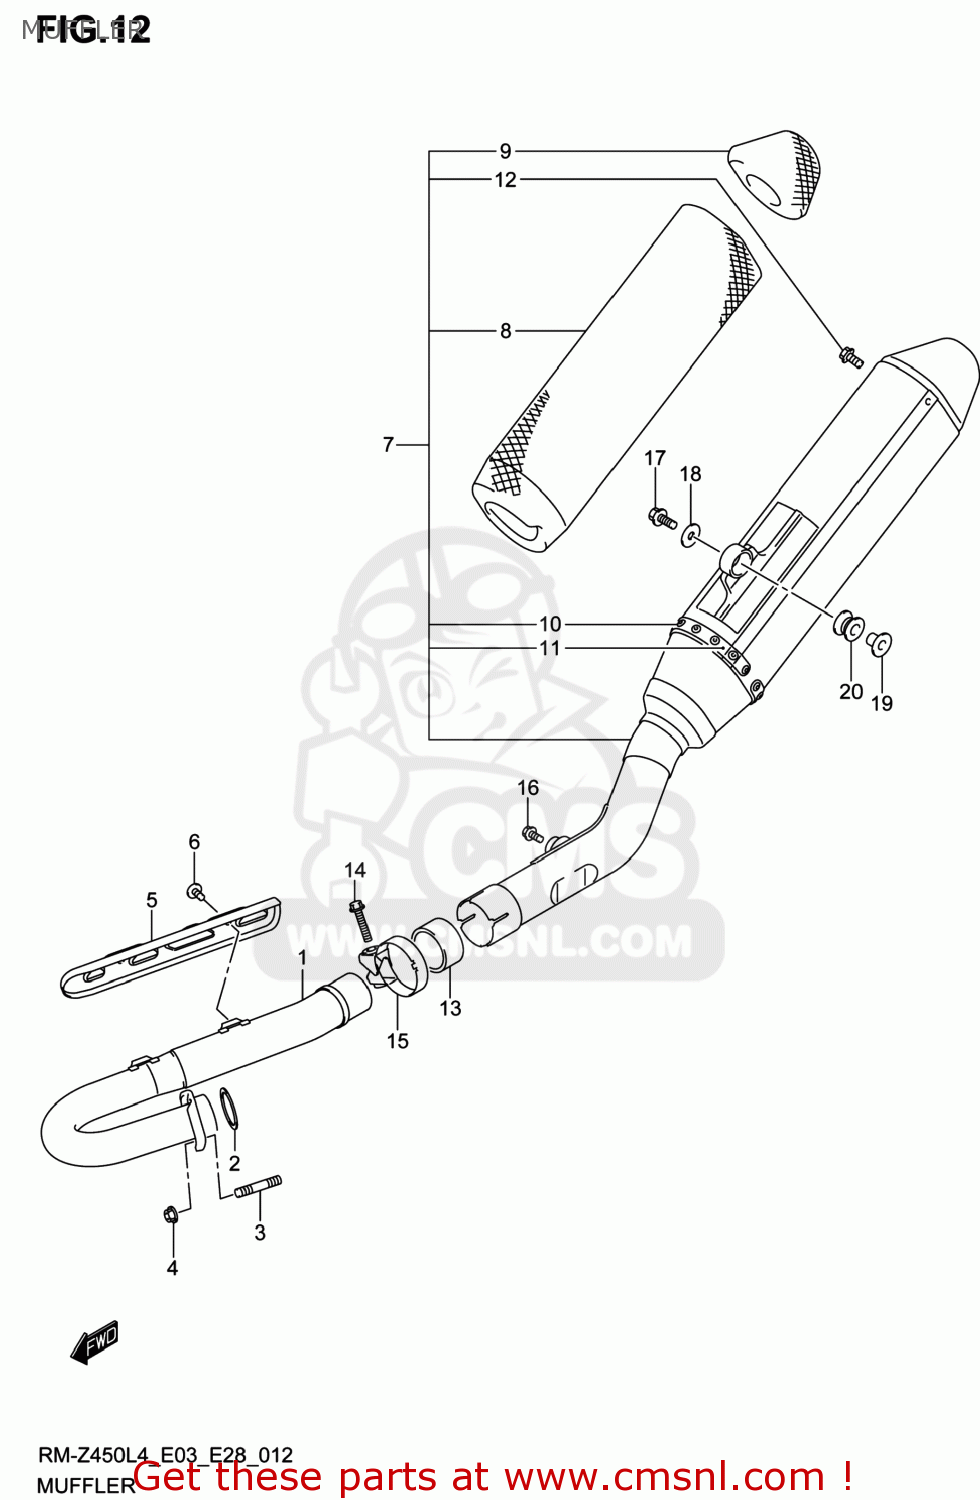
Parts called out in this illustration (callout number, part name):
1	PIPE,EXHAUST
2	GASKET,EXHAUST PIPE (NAS)
3	BOLT,STUD
4	NUT
5	COVER,EXHAUST PIPE
6	BOLT(6X8)
7	BODY,MUFFLER
8	SILENCER,MUFFLER
9	GLASS WOOL,MUF TAIL
10	RIVET,MUFFLER
11	BAND,MUFFLER
12	BOLT
13	CONNECTOR,MUFFLER
14	BOLT(8X35)
15	CLAMP,CONNECTOR
16	BOLT(8X20)
17	BOLT(8X35)
18	WASHER(8.5X26X1.6)
19	SPACER(8.6X12X18.5)
20	CUSHION
